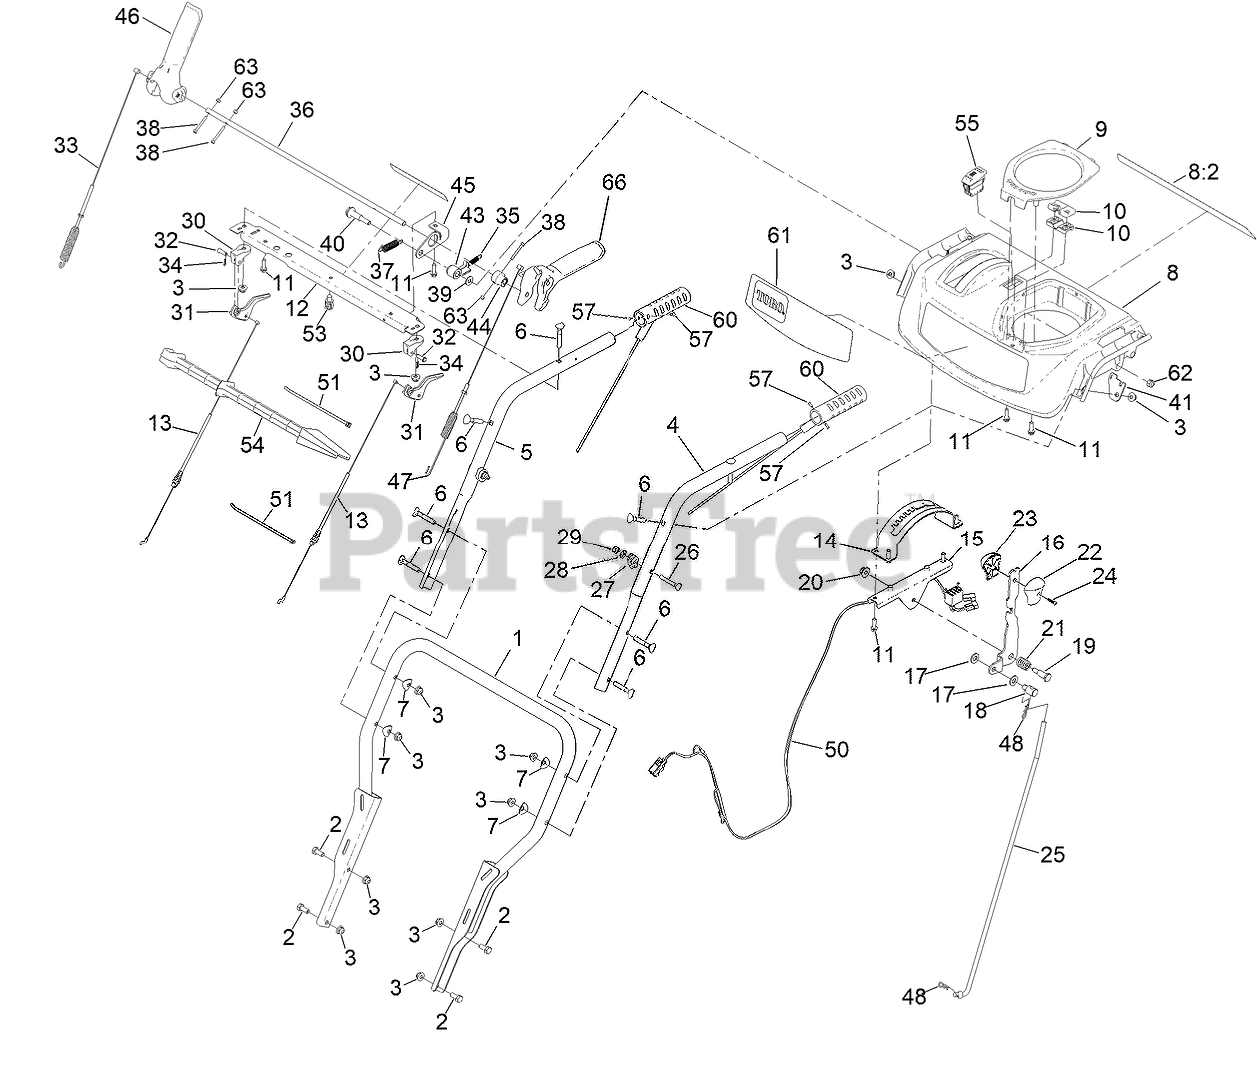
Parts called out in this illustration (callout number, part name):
1	LOWER HANDLE ASM
2	SCREW-HH
3	NUT-HF
4	HANDLE-UPPER, LH
5	HANDLE-UPPER, RH
6	SCREW-HANDLE
7	WASHER-CUP
8	PANEL-CONTROL, ASSEMBLY
8:2	DECAL-SAFETY
9	COVER-QUICKSTICK
10	SUPPORT-ROD
11	SCREW-PLASTITE, HWH
12	BRACE-CONSOLE
13	CABLE-CLUTCH
14	GATE-SHIFT
15	BRACKET-SHIFT
16	SELECTOR-SPEED
17	WASHER-FLAT
18	TRUNNION-ROD
19	SCREW-SHOULDER, HH
20	NUT-HF
21	SPRING-COMPRESSION
22	KNOB-SHIFT, LH
23	KNOB-SHIFT, RH
24	SCREW-PPH
25	ROD-SHIFT
26	BOLT-CARR
27	CLAMP-CABLE
28	WASHER-FLAT
29	NUT-HEX
30	MOUNT-LEVER, CLUTCH
31	LEVER-CLUTCH
32	PIN-CLEVIS
33	CABLE-AUGER
34	PIN-HAIR
35	SPRING-LOCKOUT, HANDLE
36	ROD-LOCKOUT
37	SPRING-RETURN, LEVER
38	SCREW-HSH,SPL
39	WASHER-FLAT
40	SCREW-SHOULDER
41	PLATE-SPRING
43	LATCH, LOCKOUT
44	CAM-LOCKOUT
45	BRACKET-INTERLOCK
46	LEVER-CONTROL
47	CABLE-TRACTION
48	PIN-HAIR
50	HARNESS-WIRE, LED AND HAND WARMERS
51	TIE-CABLE
53	CLIP-TIE
54	STICK-CLEANOUT
55	SWITCH-ROCKER, ON-NONE-OFF (HEATER)
57	RIVET-POP
60	RED HEATED GRIP
61	DECAL-CONSOLE
62	NUT-HEX
63	NUT-LOCK ROHS
66	LEVER-CONTROL
